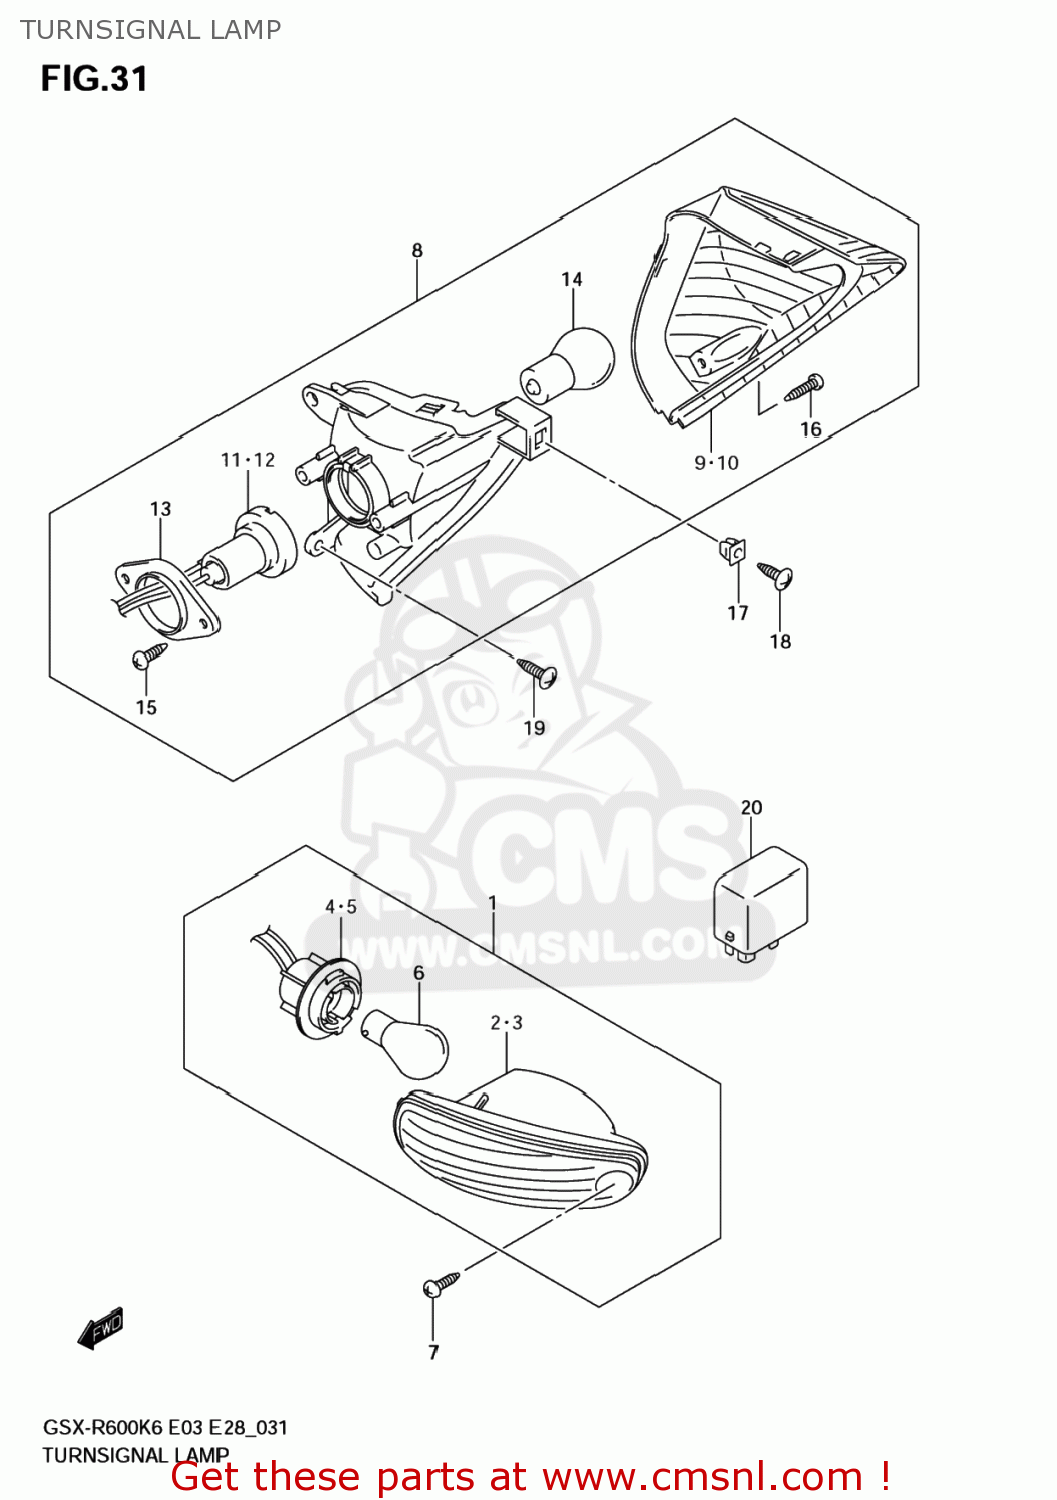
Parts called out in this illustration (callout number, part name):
1	LAMP ASSY,FR TURN SIGNAL,R
2	LAMP UNIT,R
3	LAMP UNIT,L
4	SOCKET,R
5	SOCKET,L
6	BULB(12V21W,AMBER)
7	SCREW(4X20)
8	LAMP ASSY,RR TURNSIGNAL,R
9	LENS,R
10	LENS,L
11	SOCKET & CORD,R
12	SOCKET & CORD,L
13	PLATE,RR COMBINATION
14	BULB(12V21W,AMBER)
15	SCREW
16	SCREW
17	NUT
18	SCREW
19	SCREW
20	RELAY ASSY,TURNSIGNAL LAMP
